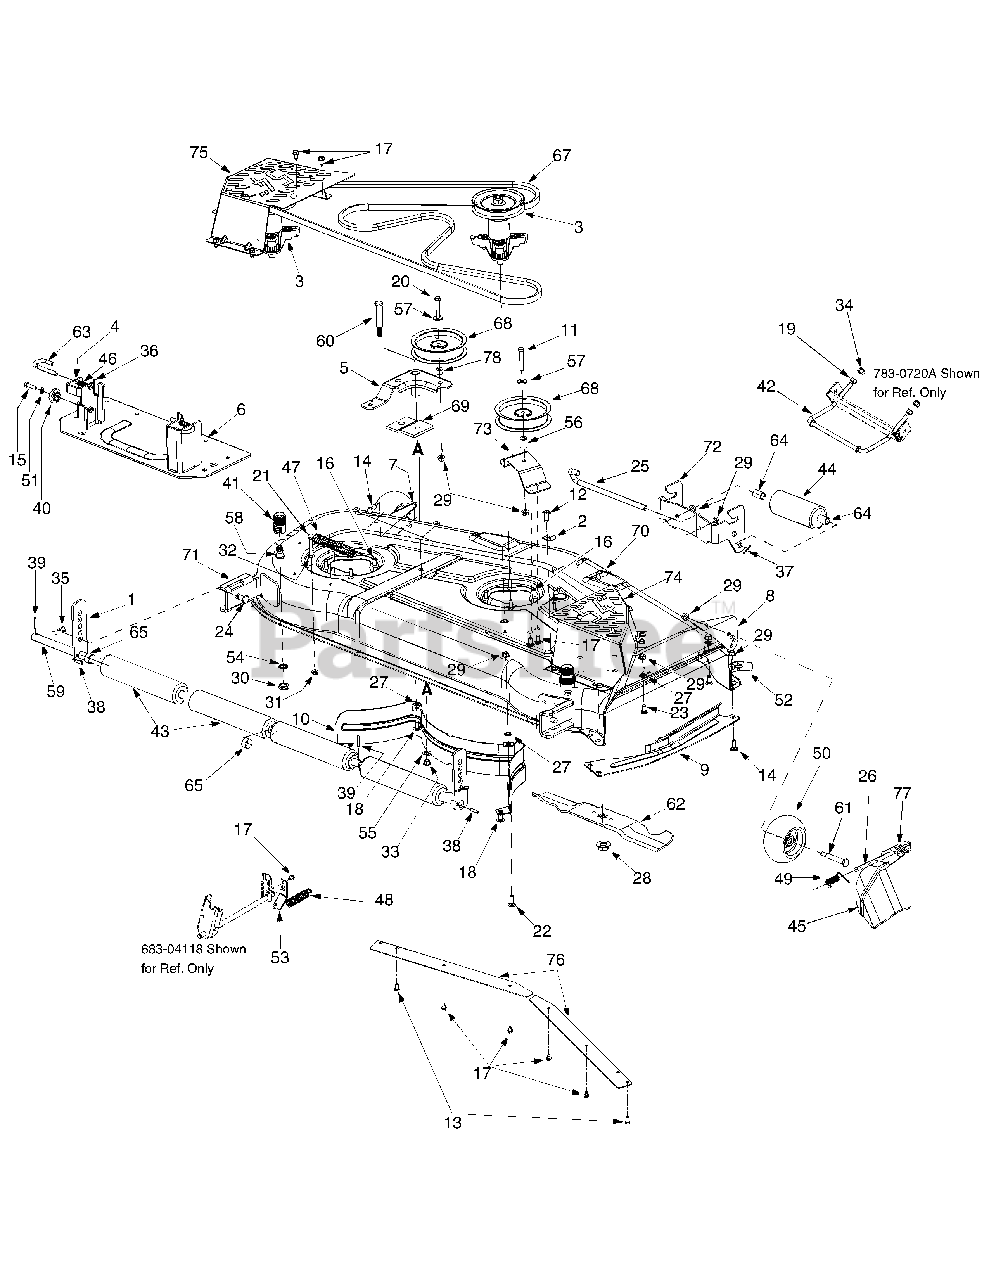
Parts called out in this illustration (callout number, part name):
2	Bracket, Hook, Retainer
3	Spindle Assembly, Pulley
8	Bracket Assembly, RH-Front
11	Screw, 3/8-16 x 3.00
12	Screw, 1/4-20 x.500
13	Hex Screw 3/8-16 x 0.75
14	Hex Screw 3/8-16 x 1.0
15	Hex Screw, 5/16-18 x 1.25
16	LD Screw 5/16-18 x 0.75
17	Screw, 5/16-18 x 0.500
18	Screw, 3/8-16 x.750
19	Hex Nut, 1/2-13
20	Hex Screw, 3/8-16 x 2.25
21	Hex Screw, 5/16-18 x 2.00
22	Bolt, Carriage, 3/8-16 x 1.0
23	Short Neck Carriage Bolt 3/8-16 x.75
24	Pin, Clevis,.50 Dia x.78
25	Pin, Roller,.5" Dia x 10.06.
26	Pin, Hinge, Dia.3125
27	Push Nut Retainer
28	Nut, Hex Flange, 5/8-18
29	Nut, Lock, Flange, 3/8-16
31	Nut, Flange Lock, 5/16-18
32	Nut, Hex, 5/16-18, Gr5
33	Nut, Hex Lock, 1/2-13
34	Hex Lock Nut, 1/2-13
35	Pin, Click,.092 x 1.64
36	Pin, Cotter, 1/8 x 1.25
37	Pin, Cotter, 3/32 x 1.00
38	Pin, Spring 1/4 Dia x 1.00
40	Adjustment, Deck, Gear
41	Water Nozzle Adaptor
42	Rod, Deck Adjust
43	Roller, Deck
44	Front Roller
45	Deflector, Chute
46	Spring, Compression,.406 x.531 x 1.75
47	Spring, Extension,.94 Dia x 6.74
48	Spring, Extension, 1.010 Dia x 6.500
49	Torsion Spring.44 I.d. x 2.10
50	Deck Wheel, 5" Dia.
51	Lock Washer
53	Lift Bracket
56	Spacer,.380 x.900 x 1.313
57	Washer, Flat.406 x.875 x.059
58	Water Nozzle: Deck Wash-Out System
59	Shaft,.750 x.47.12
60	Shoulder Screw
61	Shoulder Screw
62	Blade, 18.50"
63	Deck Release Handle Rod,.375 Dia
64	Spacer.550 ID x.755 OD x 1.1
65	Spacer,.82 ID x 1.00 OD x.53
67	Belt, V-Type, B Section
68	Pulley, Idler, 4.25 Dia.
71	Bracket, Mounting, 54" Roller
77	Bracket, Deflector Chute
78	Spacer,.385 ID x.88 x.64
